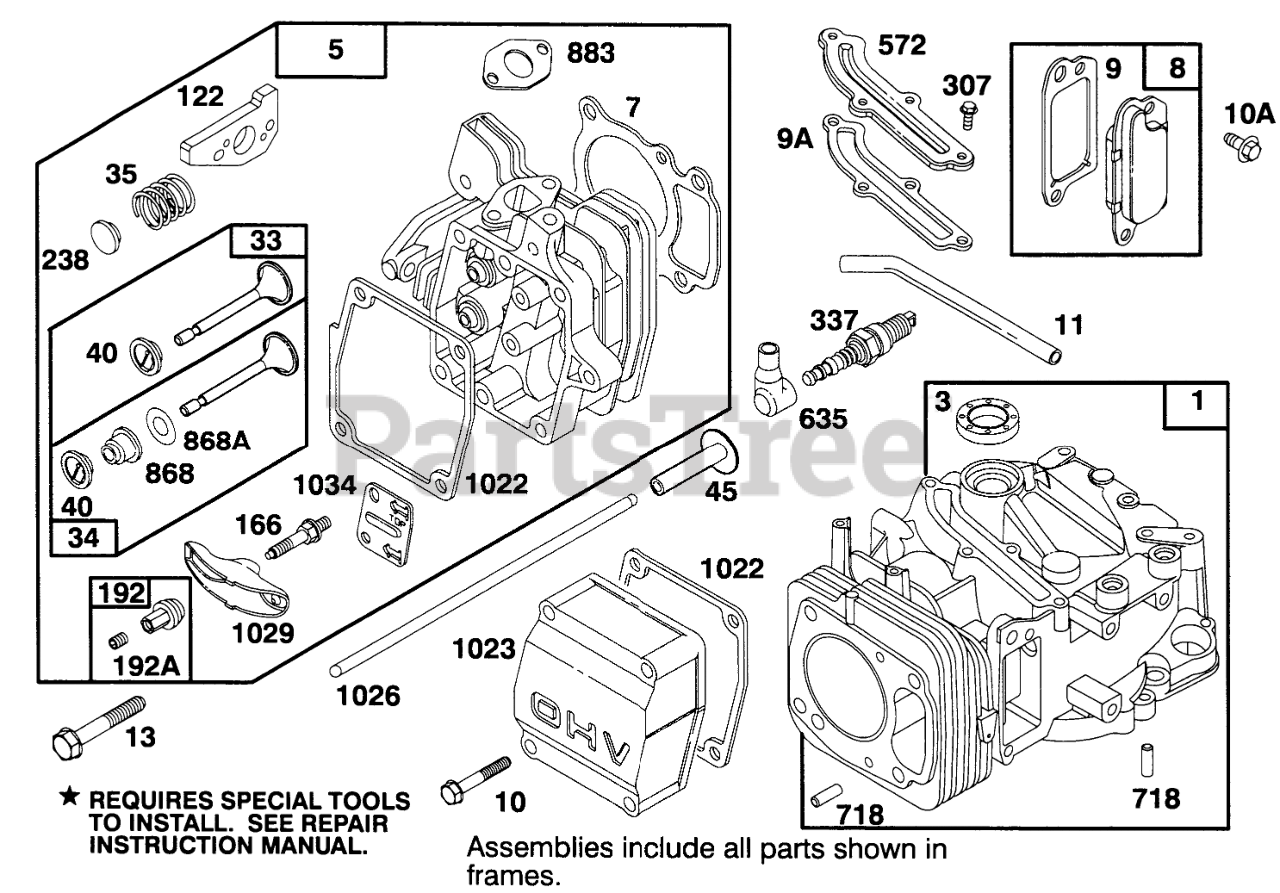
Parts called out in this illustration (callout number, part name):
1	CYLINDER ASSEMBLY
3	SEAL - OIL
5	CYLINDER HEAD
7	CYLINDER HEAD GASKET
8	Breather Assy
9	BREATHER GASKET
9A	GASKET-BREATHER
10	HEX HEAD SCREW
10A	HEX HEAD SCREW
11	TUBE - BREATHER
13	CYLINDER HEAD SCREW
33	EXHAUST VALVE
34	INTAKE VALVE
35	VALVE SPRING
40	SPRING RETAINER
45	VALVE TAPPET
122	ADAPTER ASSEMBLY
166	ROCKER ARM STUD
192	NUT - HEX SPECIAL
192A	SCREW SET
238	VALVE CAP
307	SCREW - SEM
337	PLUG-SPARK
572	BAFFLE - CYCLINDER
635	SPARK PLUG ELBOW
718	DOWEL - SLEEVE
868	SealAssy-Valve
868A	Seal-Valve
883	EXHAUST GASKET
1022	ROCKER COVER GASKET
1023	COVER - VALVE
1026	PUSH ROD
1029	ROCKER ARM
1034	PUSH ROD GUIDE
